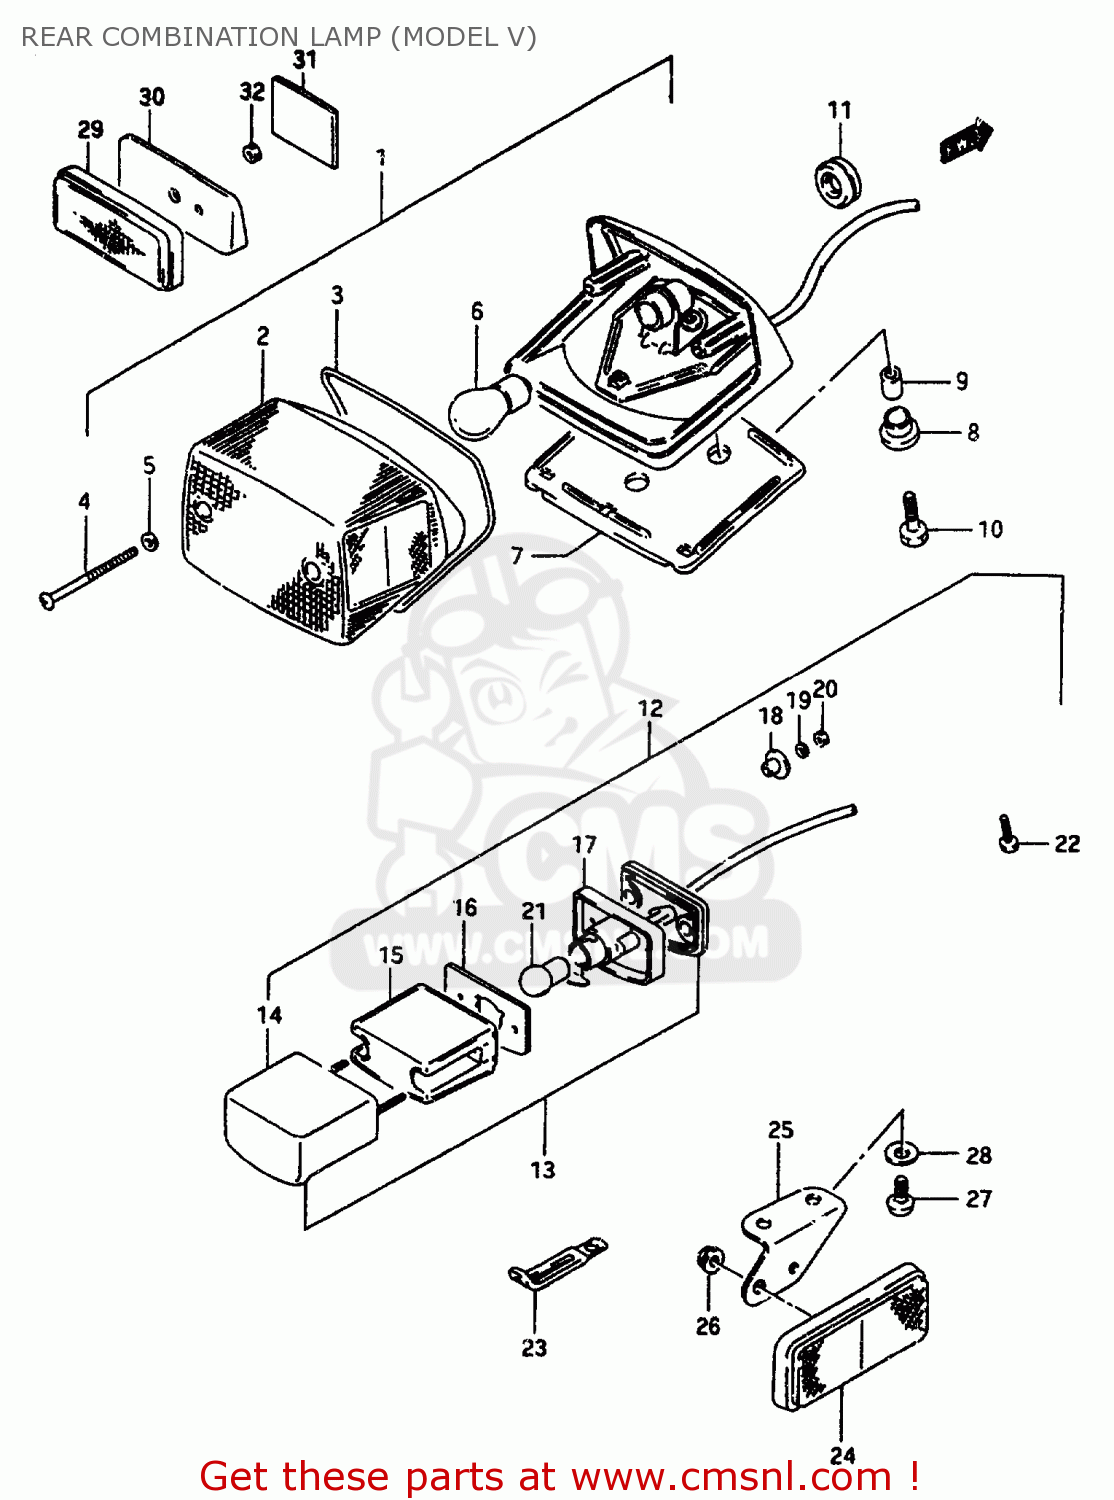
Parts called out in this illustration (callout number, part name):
1	LAMP ASSY,RR COMBINATION
2	LENS
3	GASKET (NAS)
4	SCREW
5	GASKET (NAS)
6	BULB(12V21/5W)
7	CUSHION
8	CUSHION
9	SPACER
10	BOLT(6X25)
11	GROMMET
12	LAMP ASSY,LICENSE
13	LAMP ASSY,LICENSE
14	COVER
15	LENS
16	GASKET,LICENSE LAMP (NAS)
17	HOUSING,LICENSE LAMP
18	SPACER
19	WASHER,LOCK
20	NUT
21	BULB(12V5W,BF150-40160A)
22	BOLT(6X20)
23	CLAMP(L:45)
24	REFLEX REFLECTOR,FR SIDE
25	BRACKET,RR SIDE RR,L
26	NUT
27	SCREW
28	WASHER (6.3X14X1.6)
29	REFLECTOR ASSY,RR
30	SPACER,RR REFLECTOR
31	TAPE,TOOL BAG PROTECTOR
32	NUT
34	SPACER
35	COVER,HARNESS
36	NUT
37	WASHER
